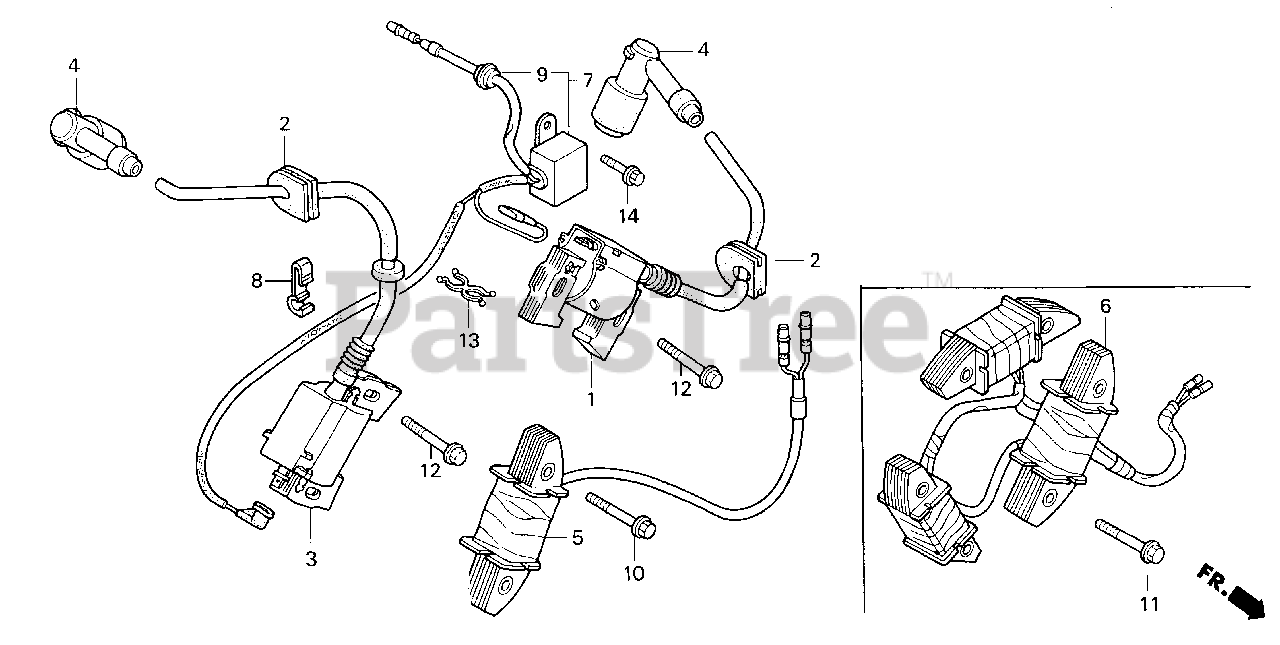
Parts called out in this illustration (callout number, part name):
1	COIL ASSY., R. IGNITION
2	GROMMET, IGNITION WIRE
3	COIL ASSY., L. IGNITION
4	CAP ASSY., NOISE SUPPRESSOR
6	COIL ASSY., CHARGE (12V/20A)
7	DIODE ASSY., ENGINE STOP
8	CLAMP, WIRE
9	GROMMET, TOOL
11	BOLT, FLANGE (6X32)
12	BOLT, FLANGE (6X32)
14	BOLT, FLANGE (6X8)
